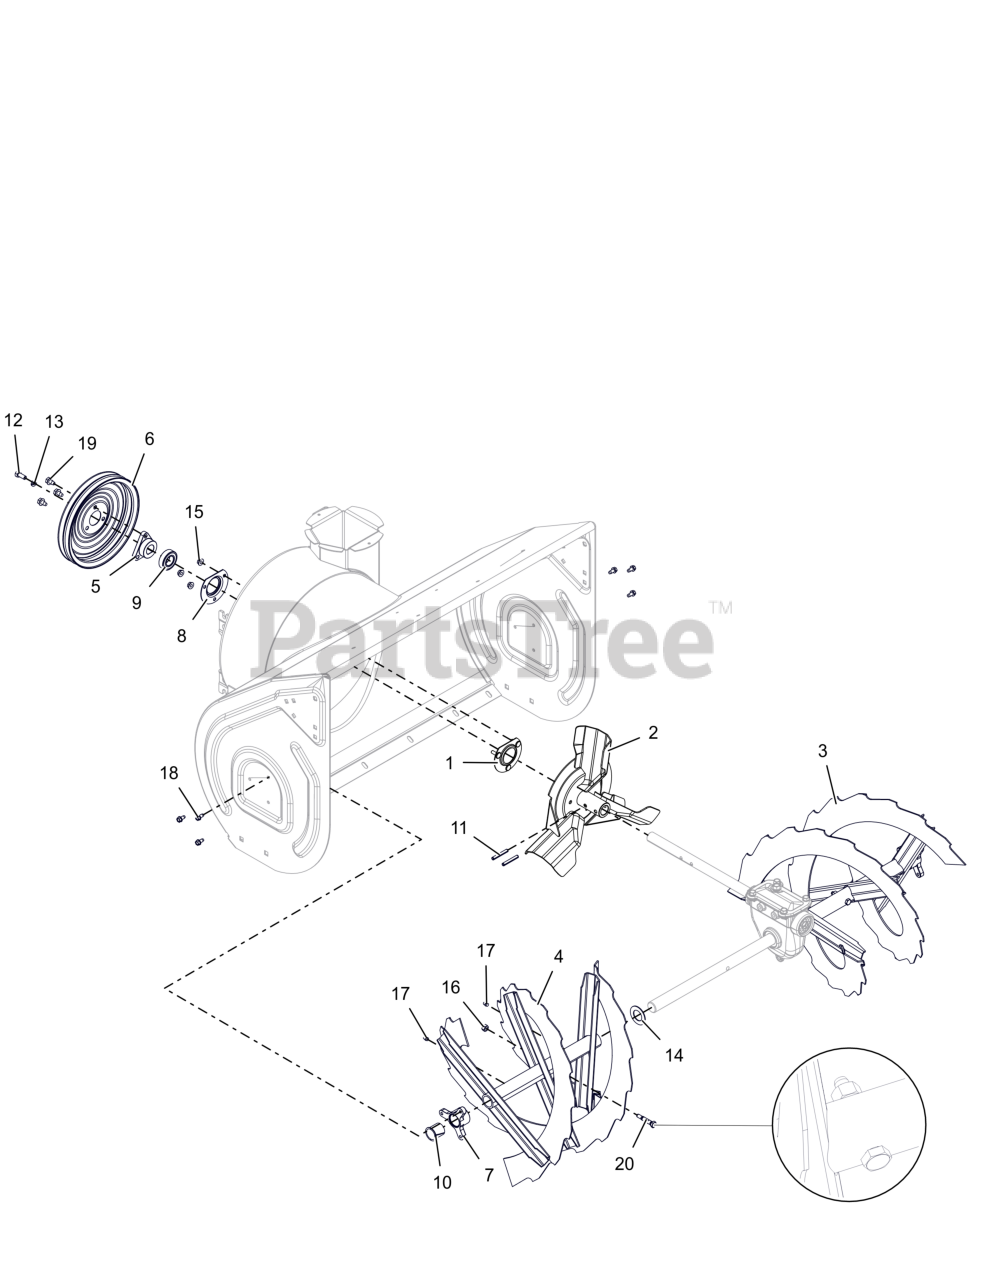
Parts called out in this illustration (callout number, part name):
1	BEARING FLANGE
2	IMPELLER, 3 BLADE-14"
3	RAKE, LH-32"(1 ID X 15.75 OD)
4	RAKE, RH-32"(1 ID X 15.75 OD)
5	PULLEY HUB, D-BORE .87 PRO
6	PULLEY, SPIN FORM DUAL GROOVE
7	BUSHING, RAKE SHAFT 1"
8	BEARING FLANGE
9	BRG-BALL .876X1.75X.50 RSTFP
10	BSHG-FLG SPLIT NYLINER 1.0" HP
11	PIN-ROLL .250X1.75
12	BLT, HEX .31-24X.750 G5 ZCC
13	WSHR, LK-HVY .312X.097 ZCC
14	WSHR- FLT 1.010X1.755X.062 ZCC
15	NUT-LK-CTR-FLG .25-20 ZC120
16	NUT,LK-CTR .31-18 GA ZCC
17	ZERK,FITTING .25X.125 DRIVE IN
18	SCR-TAP .25-20X.50 HWH ZCC
19	SCR,TAP .312-18X.50 HWH TR ZCC
20	SHEAR BOLT SERVICE ASSEMBLY (INCLUDES NUT)
